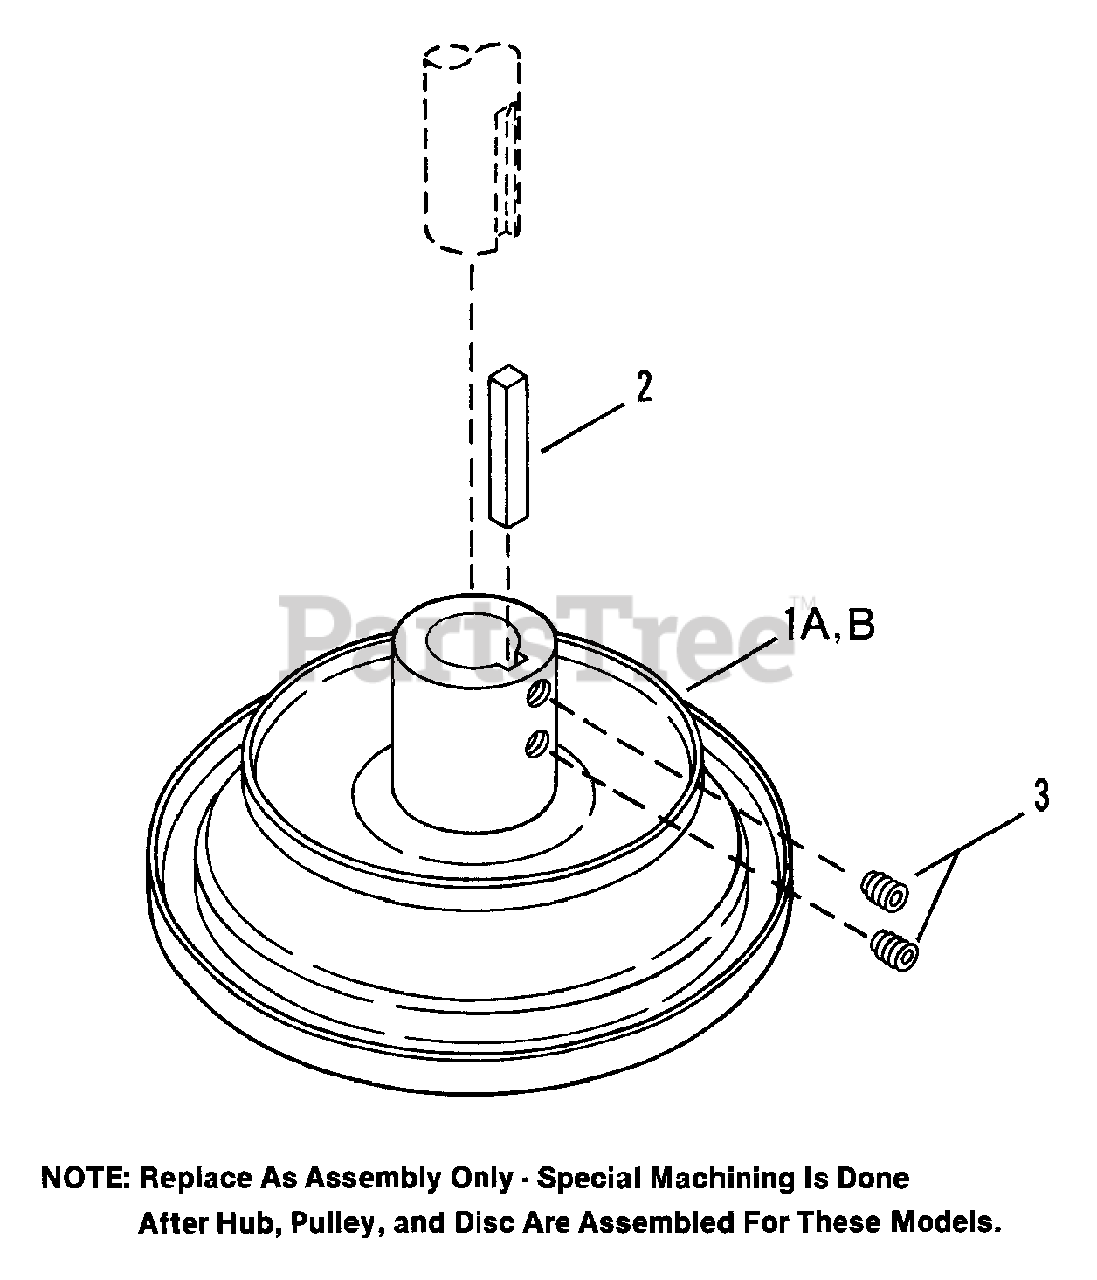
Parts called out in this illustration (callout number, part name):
1A	ASSEMBLY, Drive Disc, 4" O.D. for 30 & 33" Models
1B	ASSEMBLY, Drive disc, 5" O.D. for 25,26 & 28" Models
2	KEY, 1/4 x 1/4 2"
3	SET-SCREW, 3/8-16 x 3/8"
